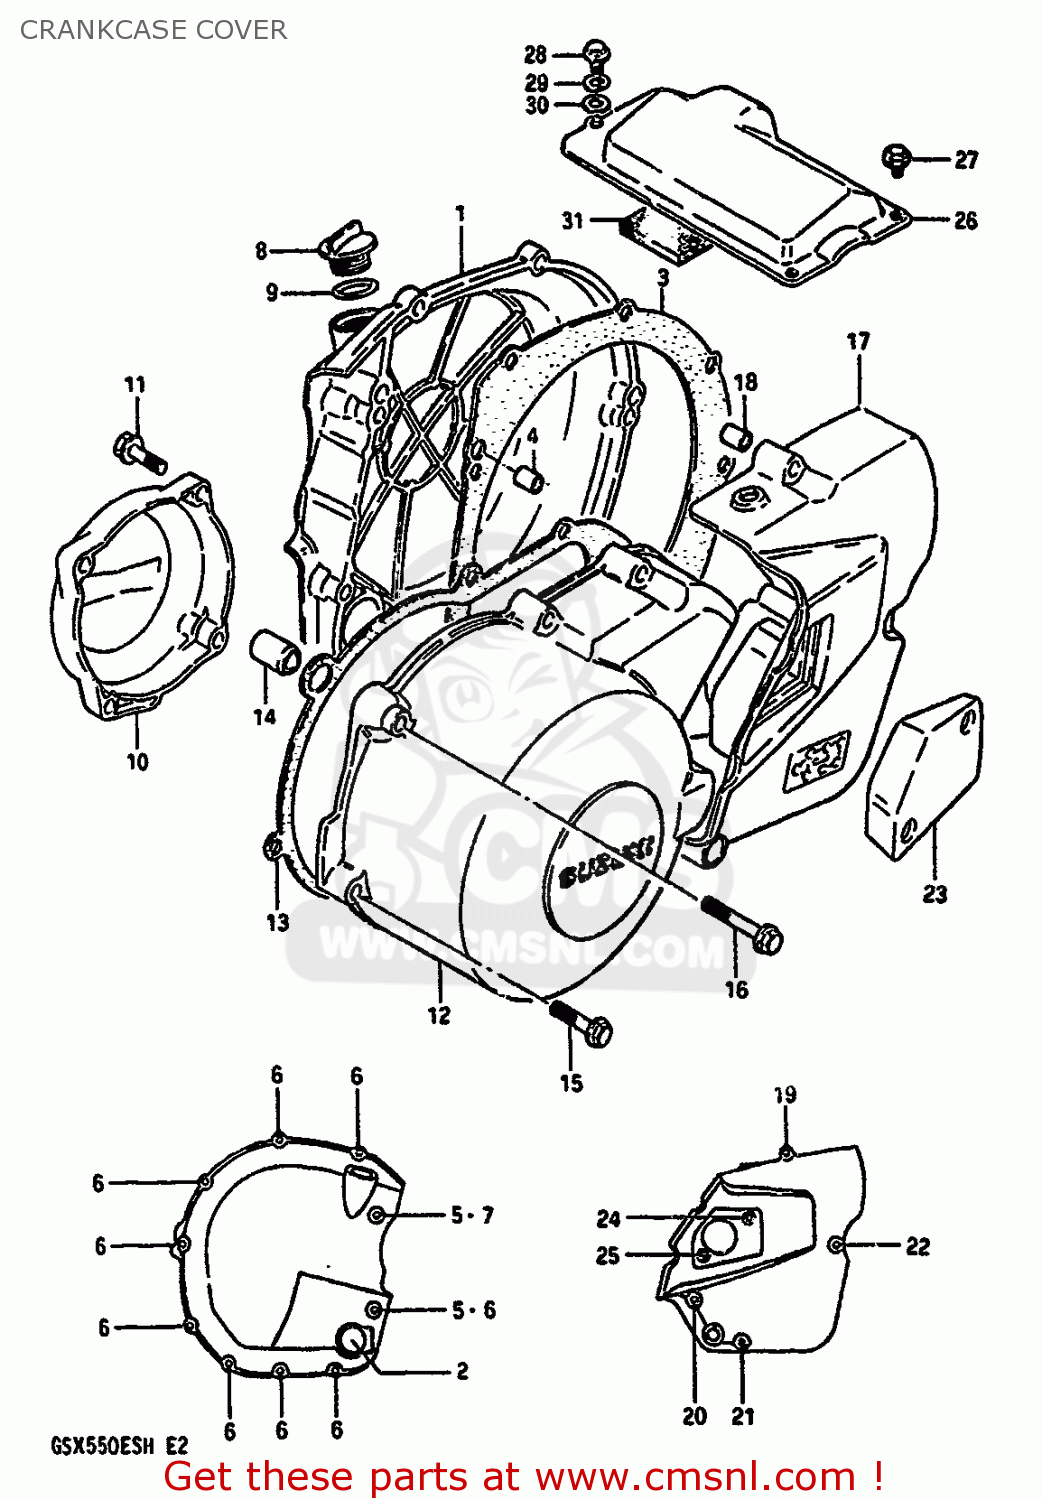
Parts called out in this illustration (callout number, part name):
1	COVER,CLUTCH
2	LENS,OIL LEVEL CHECK
3	GASKET,CLUTCH COVER (MCA)
4	PIN
5	GASKET(5.8X13X1.2) (NAS)
6	BOLT 6X25
7	BOLT 6X35
8	PLUG
9	O RING(D:3.1,ID:16.8)
10	COVER,CONTACT BREAKER
11	BOLT 6X25
12	COVER,MAGNETO
13	GASKET,MAGNETO COVER (MCA)
14	PIN (11X20)(SUS)
15	BOLT 6X30
16	BOLT
17	COVER,ENGINE SPROCKET
18	PIN
19	BOLT 6X40
20	BOLT (6X55)
21	BOLT 6X50
22	BOLT 6X80
23	CAP,CLUTCH RELEASE ADJUST
24	SCREW
25	SCREW
26	COVER,STARTER MOTOR
27	BOLT
28	BOLT
29	WASHER,LOCK
30	WASHER
31	DAMPER,STARTER MOTOR CLUTCH
